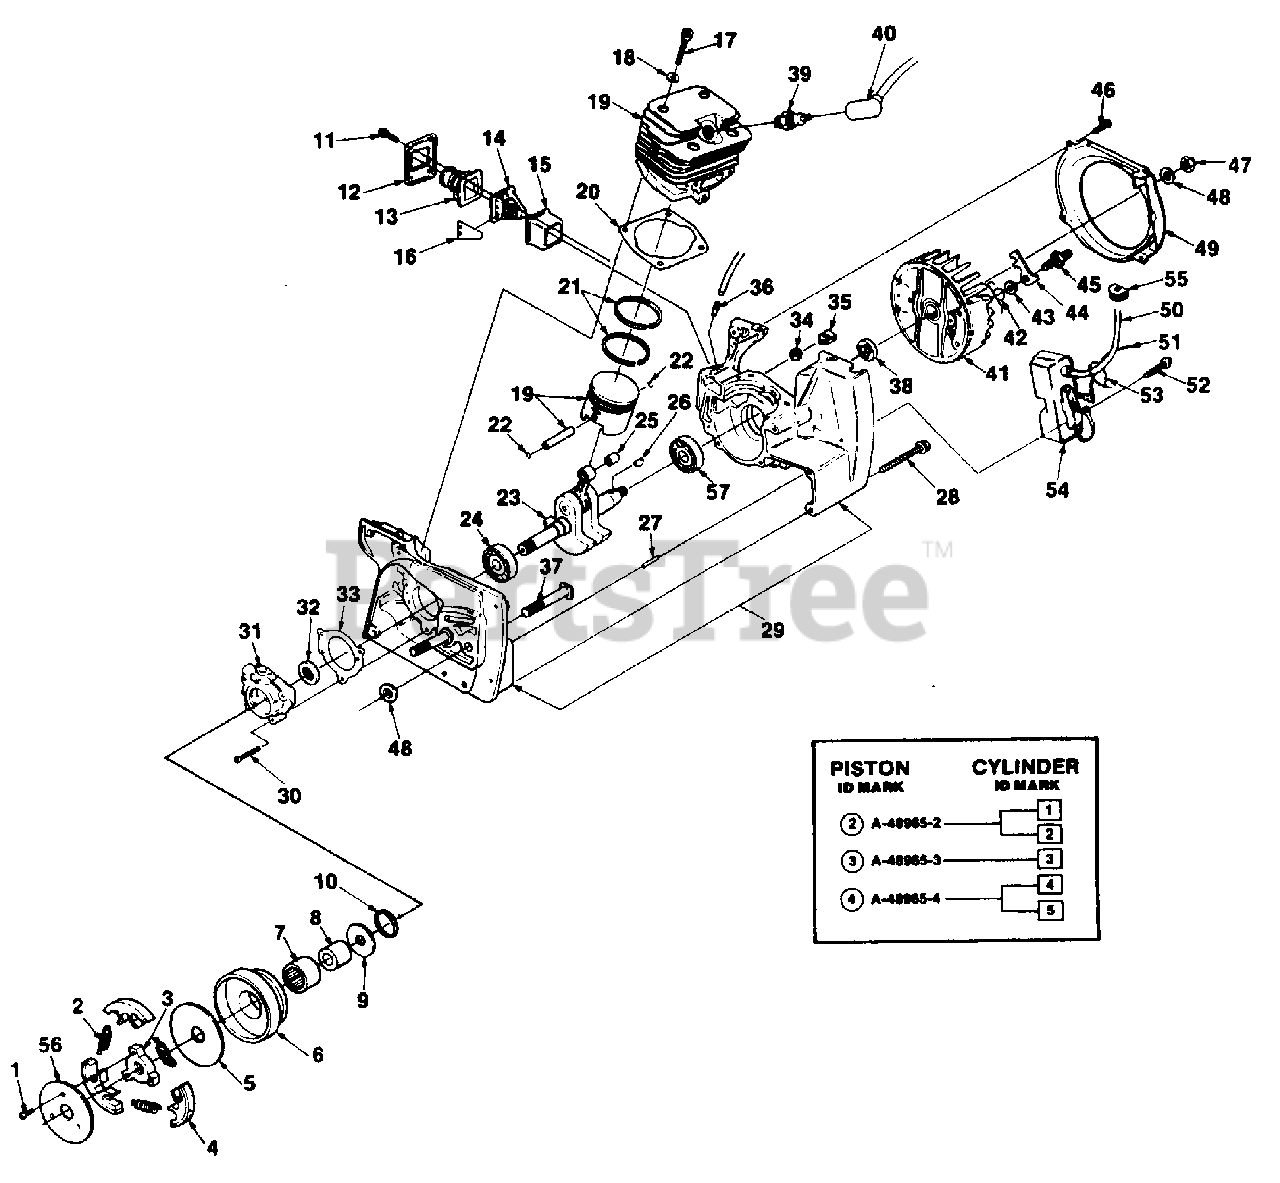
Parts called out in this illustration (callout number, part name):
2	SPRING- Clutch
3	SPIDER- Clutch
4	SHOE- Clutch
5	WASHER- Thrust
6	PULLEY- Drum & Bearing
7	BEARING- Needle
8	RACE- Inner
9	WASHER- Thrust
11	SCREW- 8-32 x 5/8
12	RETAINER- Reed valve
13	CONNECTOR- Carburetor
14	SEAT- Reed valve
15	RETAINER- Reed
17	SCREW- Cap socket head
18	WASHER- Conical
19	PISTON & CYLINDER (See Note 2)
20	GASKET- Cylinder
21	PISTON RING
22	RING- Retaining
23	CRANKSHAFT
24	BEARING- Ball
25	BEARING- Roller
26	KEY- Woodruff
27	PIN- Dowel
28	SCREW- 10 - 24 x 1.750
29	CRANKCASE
31	BEARING- Retainer
33	GASKET- Bearing retainer
35	NUT- Retainer
36	FITTING- Tubing
37	BOLT
38	SEAL- Shaft
39	SPARK PLUG (Champion DJ7Y)
40	TERMINAL- Spark plug
41	ROTOR- 4.500 Dia.
42	SPRING- Starter pawl
43	WASHER- Lock #2
44	FINGER- Starter
45	STUD- Shoulder
46	SCREW- Mach pan hd
47	NUT- Locking hex
48	WASHER- Flat
49	SCROLL- Air guide
50	LEAD- Hi-tension (Note 1)
51	SWITCH & LEAD
53	CLAMP- Wire
55	GROMMET
56	COVER- Clutch
57	BEARING- Ball
